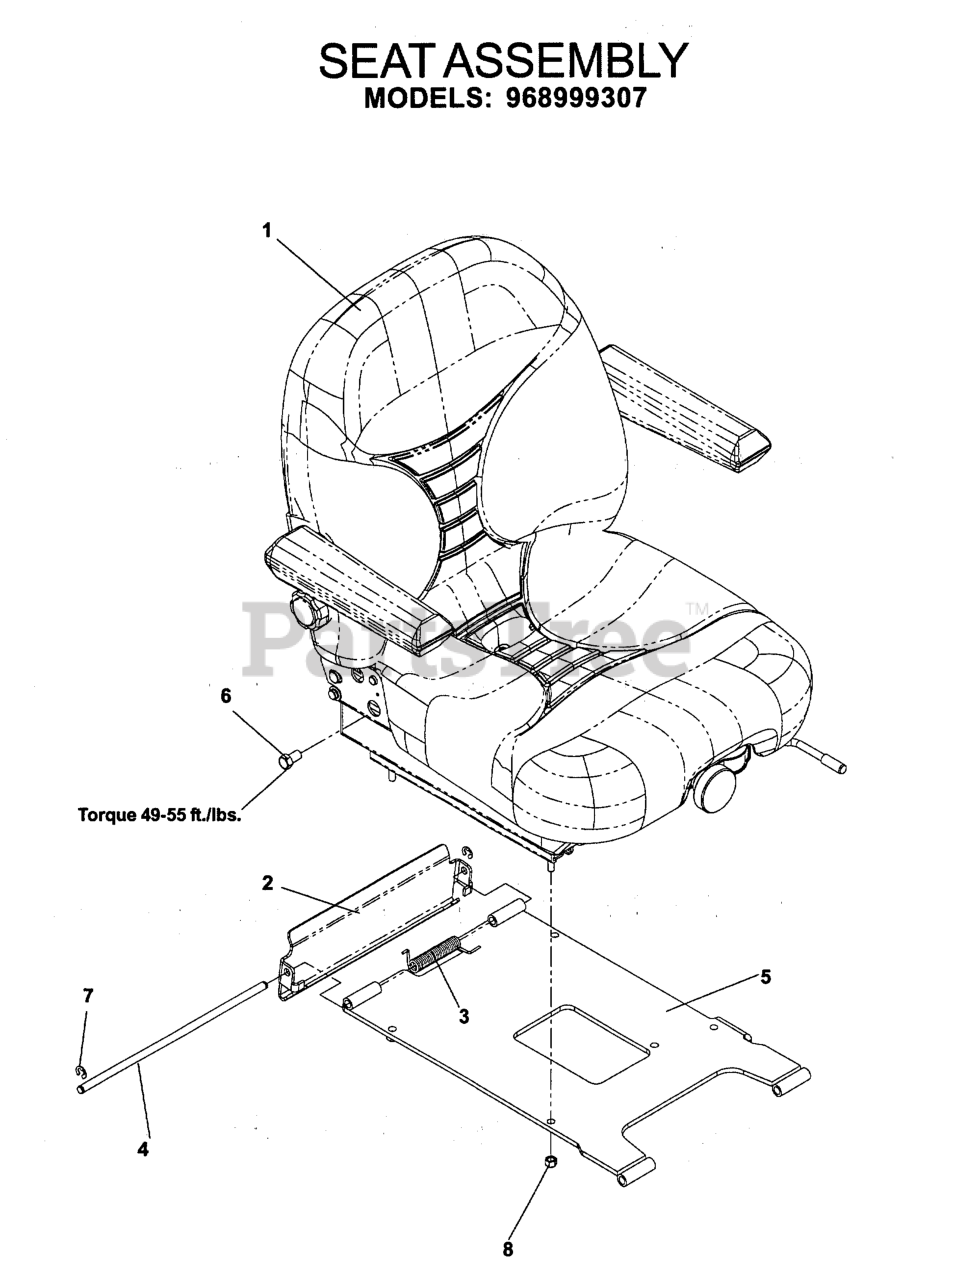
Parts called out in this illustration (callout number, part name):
1	SEAT, SUSPENSION
2	SEAT LATCH BRACKET
3	TORSION SPRING (SEAT)
4	SEAT LATCH ROD
5	SEAT MOUNTED WLDMT
6	HCS 7/16-20 X .75 GD 5
7	E RING 3/8"
8	NUT 5/16 NYLOC
